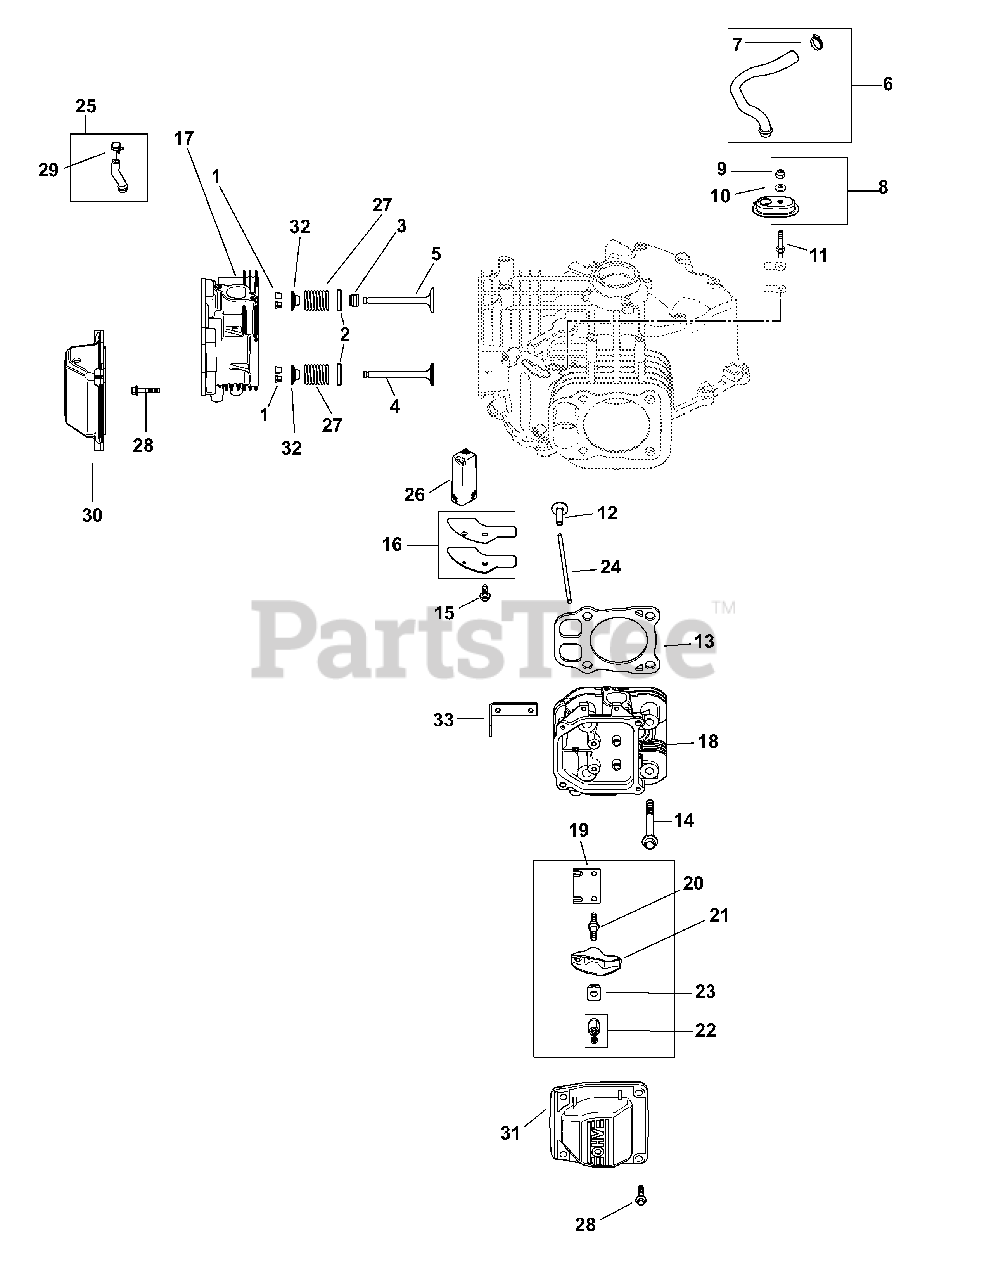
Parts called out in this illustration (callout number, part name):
1	Retainer Kit
2	Spring Retainer
3	Valve Stem Seal
4	Exhaust Valve
5	Intake Valve
6	Breather Hose Kit (Inc. 7)
7	Hose Clamp, 1/2
8	Breather Housing Kit (Inc. 9 & 10)
9	Lock Nut, M5 x .8
10	Sealing Washer
11	Breather Cover Stud
13	Cylinder Head Gasket Kit
14	Flg. Screw, M10 x 1.5 x 90
15	Flg. Thd. Frm. Screw, M6 x 1.0 x 16
16	Breather Cvr Kit (Inc. KH-32-041-S)
17	#1 Cylinder Head Assembly Kit
18	#2 Cylinder Head Assembly Kit
22	Hex Nut Assembly (Incl. set screw)
23	Rocker Arm Pivot
25	Fuel Pump Hose Kit w/Clamp
26	Breather Filter
27	Valve Spring
28	Screw, Pan Head
30	Rocker Stamped Steel Cover
31	Rocker Stamped Steel Cover
32	Valve Spring Cap
33	Lifting Strap
